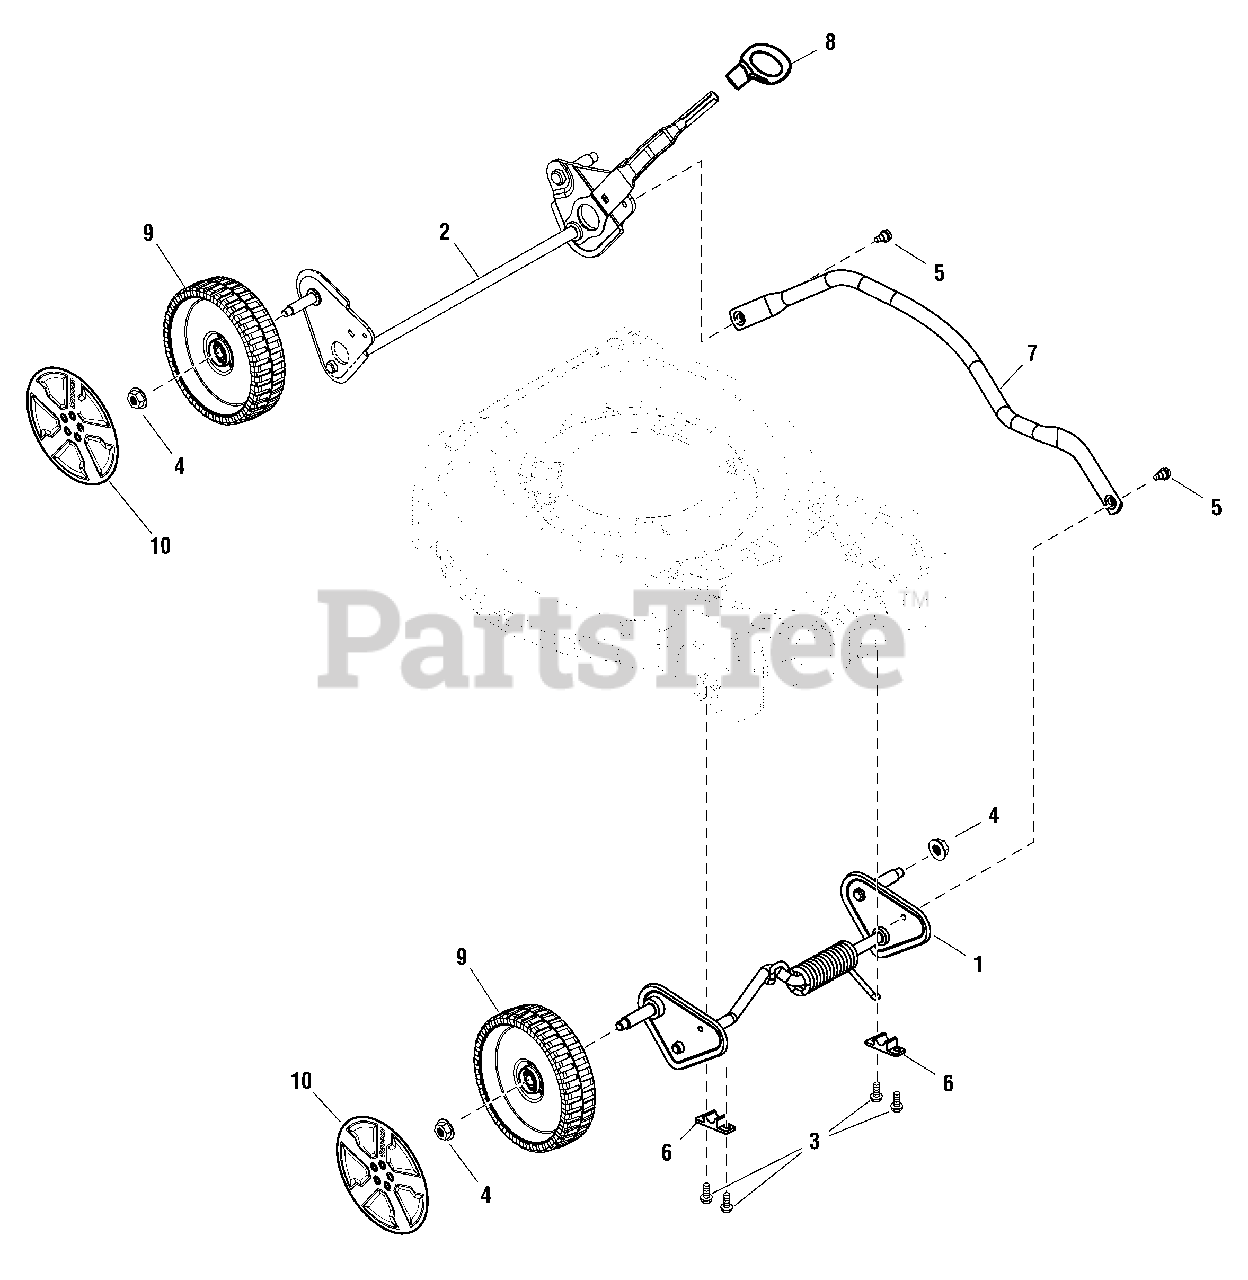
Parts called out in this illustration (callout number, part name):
1	AXLE, Front
2	AXLE, Rear
3	SCREW, 1/4-15X3/4, Self-Tapping, BZ
4	NUT, Hex Flange, Nylock, 3/8-16
5	SCREW, 1/4-20 x 1/2
6	BUSHING, Lock
8	KNOB, Red
9	WHEEL, 180 x 47
